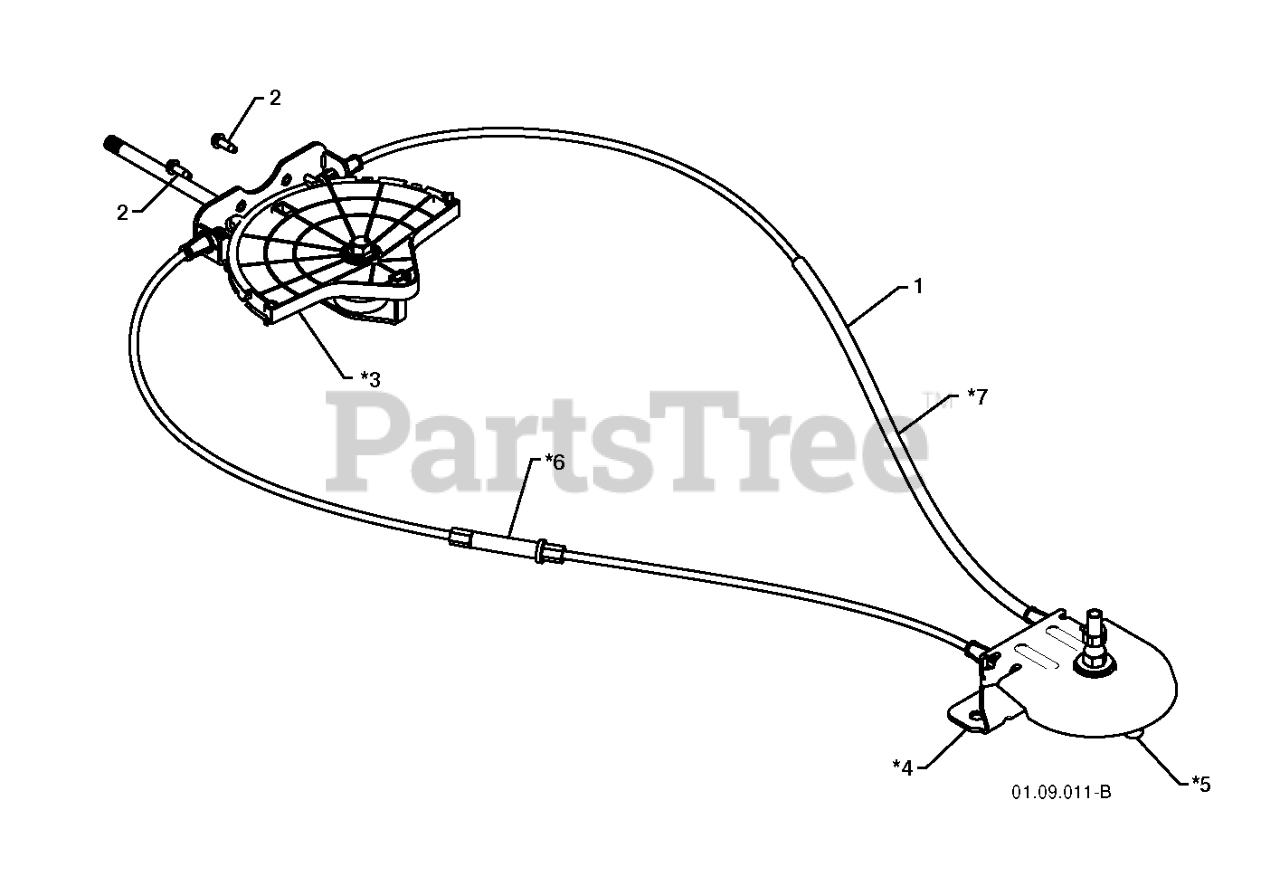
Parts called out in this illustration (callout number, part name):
1	RB LEVER.CABLE.ASM.ROTATR.PLTD
2	SCREW #10-24 X 5/8
3	CHUTE.ROT.HEAD.SERVICE
4	SNOW.PIVOT.BRKT.GRY.SERVICE
5	SNOW.PIVOT.PULLY
6	SNOW.CABLE.ASM.ADJUSTABLE.GRAY
7	SNOW.CABLE.ASM.SERVICE
